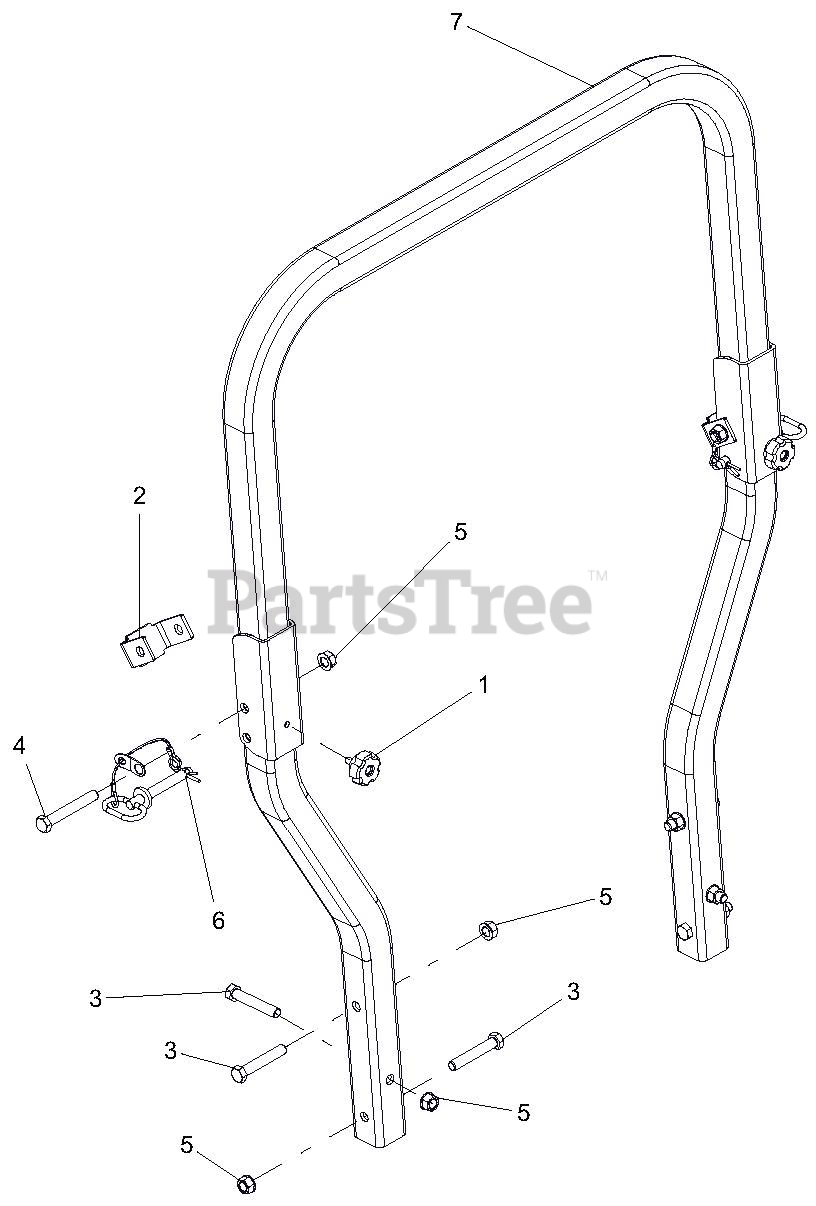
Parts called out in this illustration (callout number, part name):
1	KNOB, ROUND 5/16-18 X .750
2	BRKT, DIESEL ROPS STOP
3	BLT-HEX .50-13X3.00 GR5 YWZC
4	BLT-HEX .50-13X3.50 GR5 YWZC
5	NUT, LK-TOP-FLG .50-13 YWZC
6	ASSY, ROPS PIN/LANYARD
7	ROPS INCLUDES HOOP RH AND LH SUPPORT
